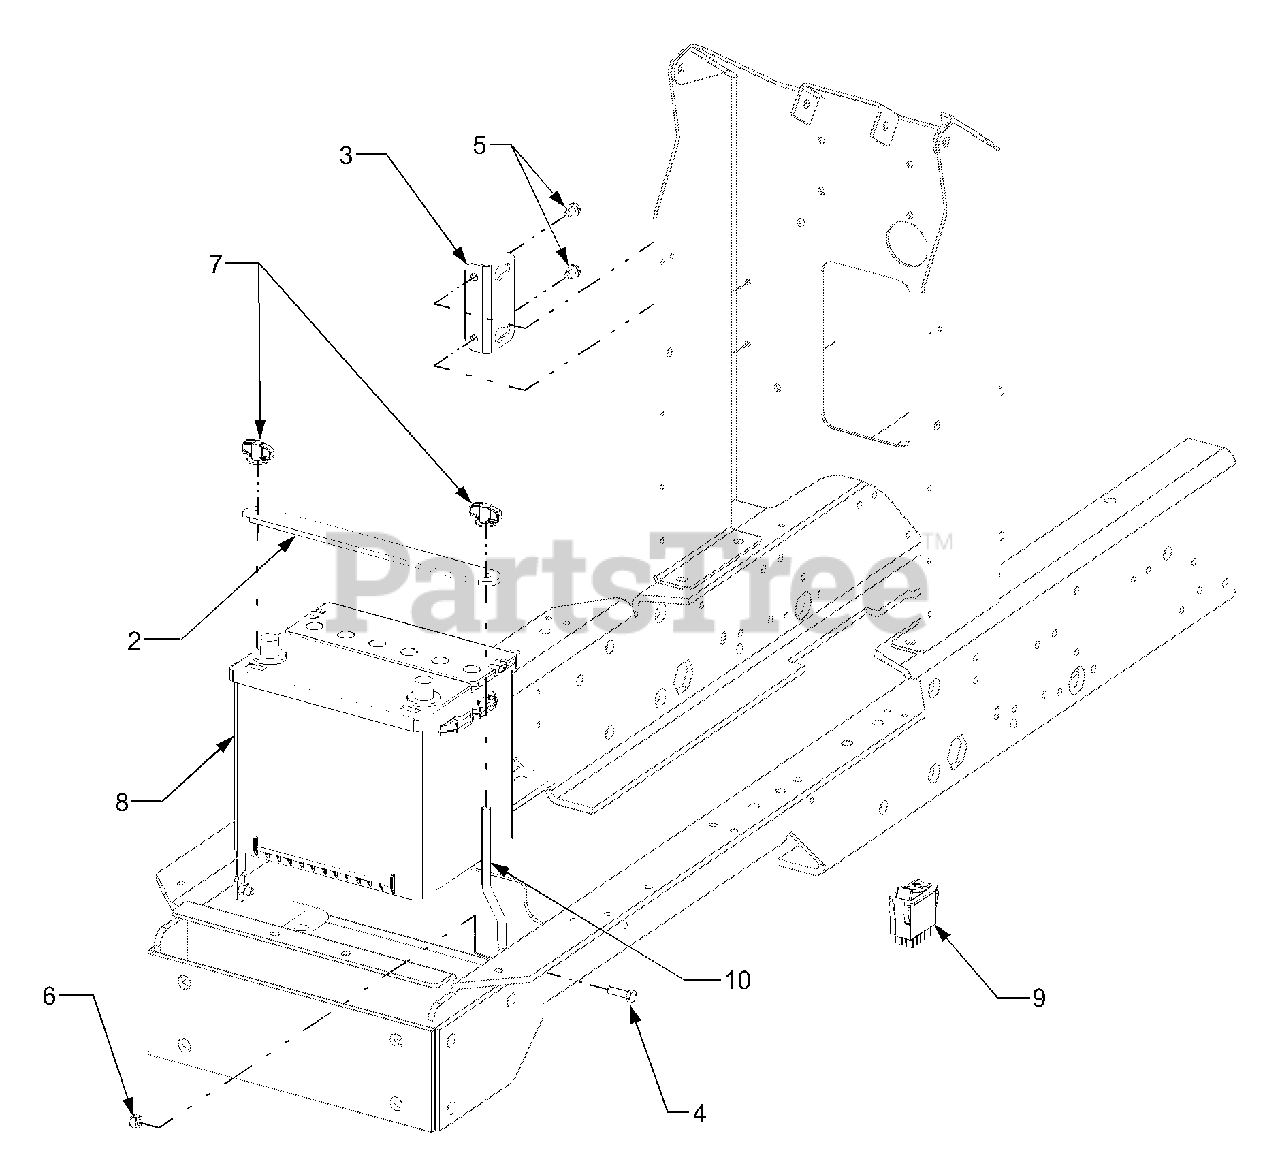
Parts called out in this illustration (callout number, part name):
2	Strap, Battery Holddown
5	Screw, Hex Wash Hd. Tapp 1/4-20 x .5
6	Nut, Hex Nylon Insert Lock, 1/4-20
7	Nut, Wing w/Bell Washer, 5/16-18
8	Battery, 500 cca Dry
9	Switch, PTO Reverse Override
10	Rod, Battery Holddown
